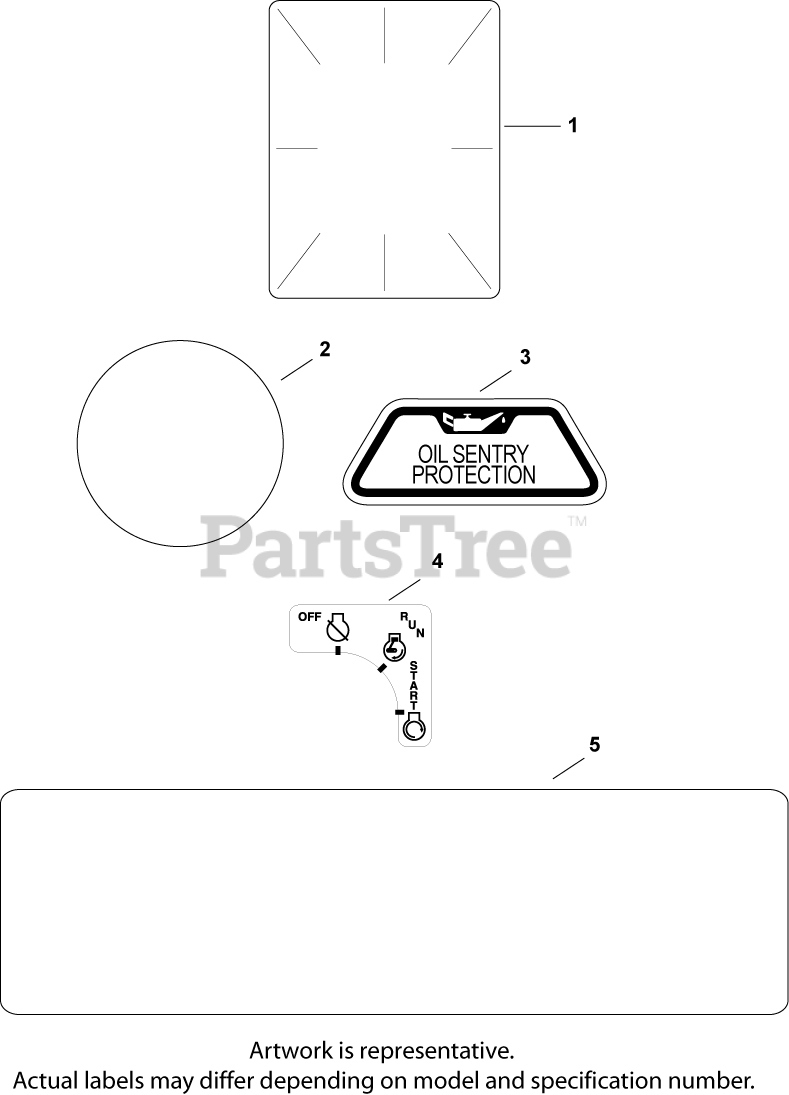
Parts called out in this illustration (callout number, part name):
1	DECAL, CLEAR LAMINATE USE 25 113 70-S
2	DECAL, GRASS SCREEN USE 24 113 499-S
3	DECAL, OIL SENTRY - (#DSC)
4	DECAL, KEY SWITCH
5	DECAL, 23 HP - DISCONTINUED
